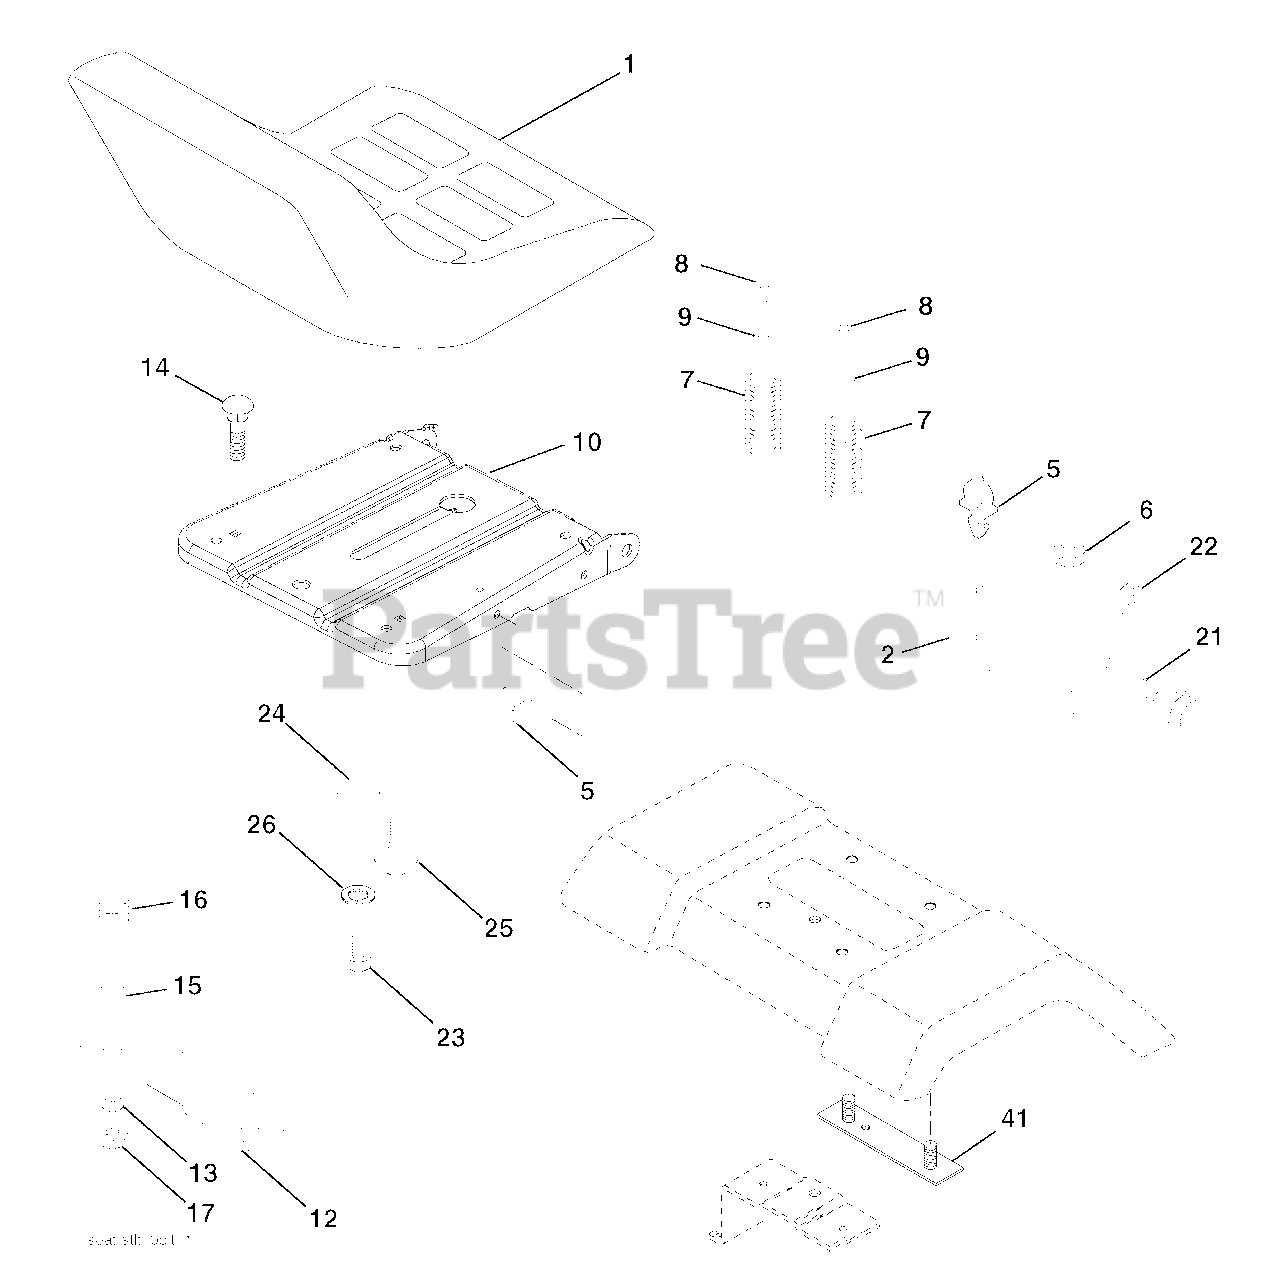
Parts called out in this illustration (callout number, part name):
1	Seat
2	Bracket Seat Pivot
5	Clip Push-In Hinged
6	Nut Lock Hex w/Ins 3/8 - 16
7	Spring Seat Cprsn 2 250 Blk Zi
8	Screw 3/8-16 x 1.5
9	Washer 13/32 x 1 x 14 Ga.
10	Pan Asm. Seat
12	Bracket Pnt Mounting Switch
13	Bushing Snap Blk Nyl
14	Bolt Rdhd Sht Nk 1/4 - 20 x 1 -1/2
15	Spacer Split .28 x .96
16	Spring Cprsn
17	Nut Lock 1/4 Lge Flg
21	Bolt Shoulder 5/16-18 unc-2A
22	Nut Lock Hex w/Ins 5/16 - 18
23	Bolt Hex
24	Washer 17/32 x 1-3/16 x 12 Ga.
25	Bolt Shoulder 5/16-18 x .62
26	Washer Lock Hvy Hlcl Spr 1/2
41	Strap Assembly
